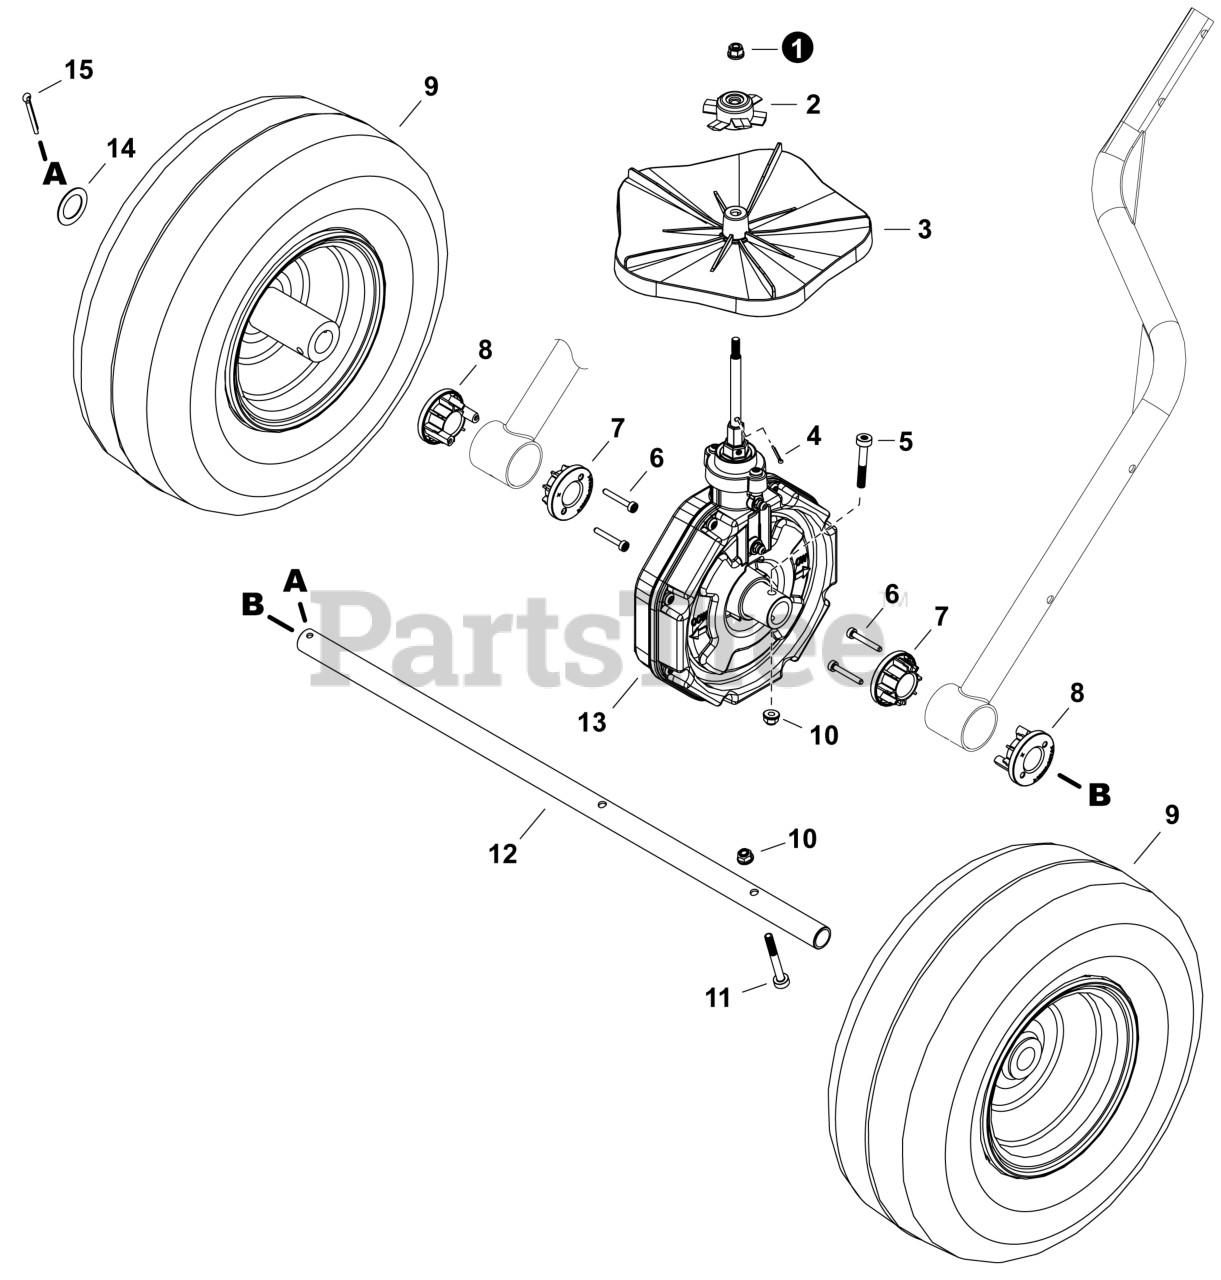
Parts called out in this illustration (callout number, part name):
2	AGITATOR - SALT
3	PLATE, SPREADER
4	PIN - COTTER
5	BOLT 6x40
7	BUSHING, AXLE
8	BUSHING, AXLE (B)
11	BOLT, M6 X 50MM
13	GEAR CASE ASSY
15	PIN - COTTER
